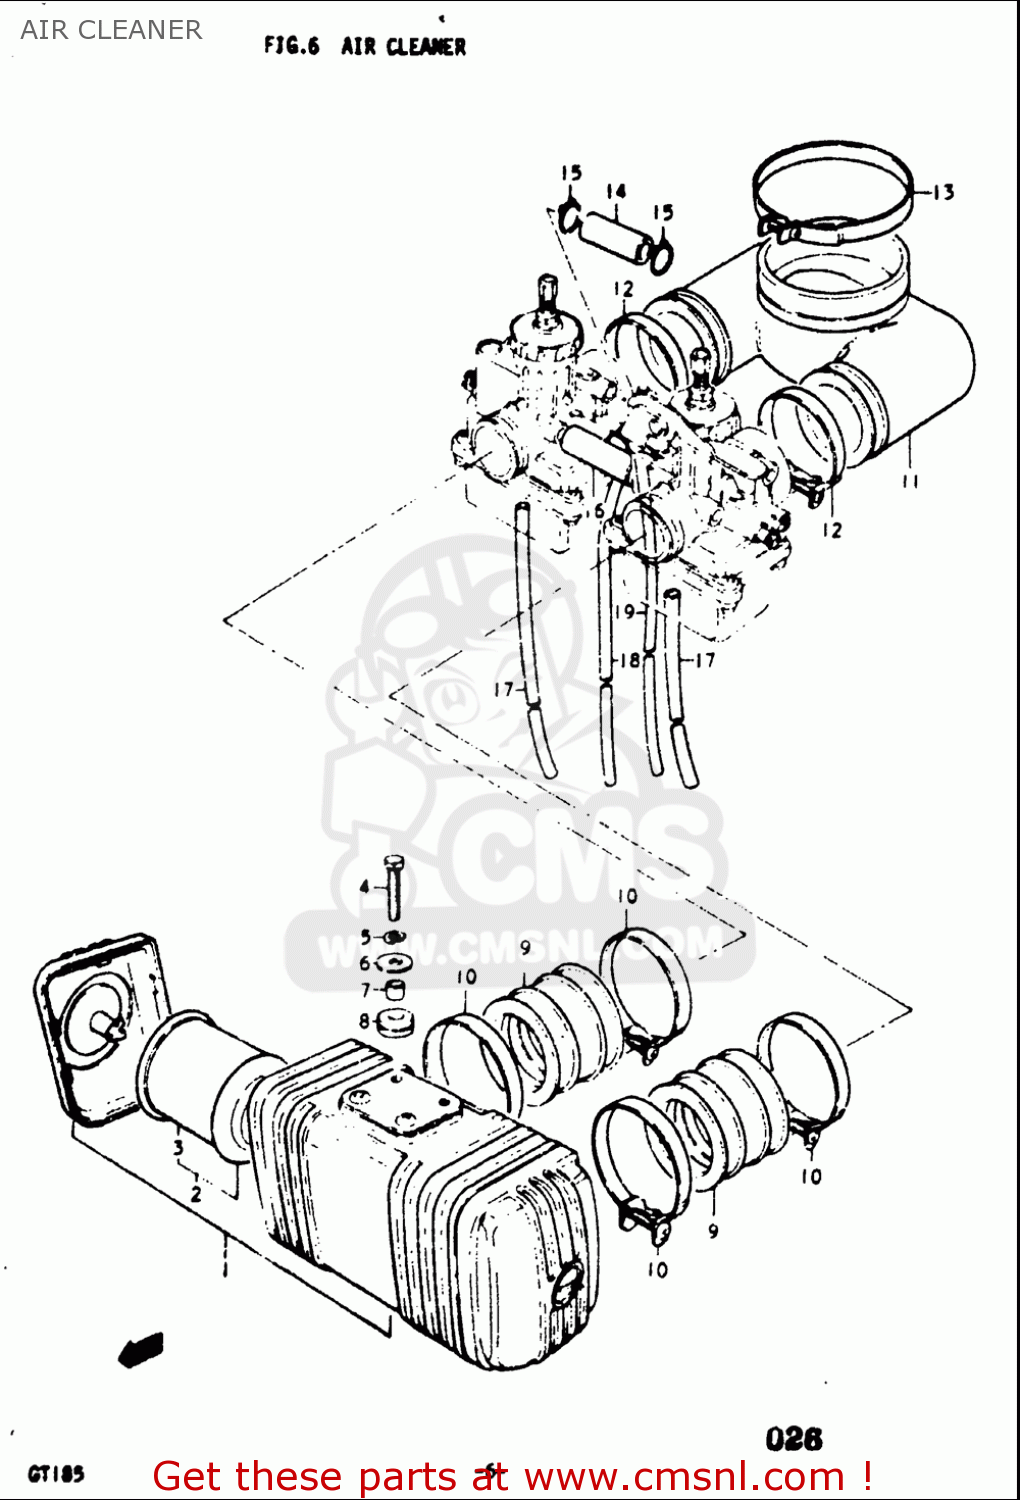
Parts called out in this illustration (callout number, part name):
2	FILTER ASSY,AIR CLEANER
3	FILTER
4	BOLT
5	WASHER,LOCK
6	WASHER(6.5X20X1.2)
8	CUSHION
9	PIPE,INTAKE
10	CLAMP
11	HOSE,CARBURETOR AIR INLET
12	CLAMP
13	CLAMP
14	HOSE(5.3X10.5X600)
15	CLIP
16	HOSE(5.3X10.5X600)
17	HOSE(3X5X600)
